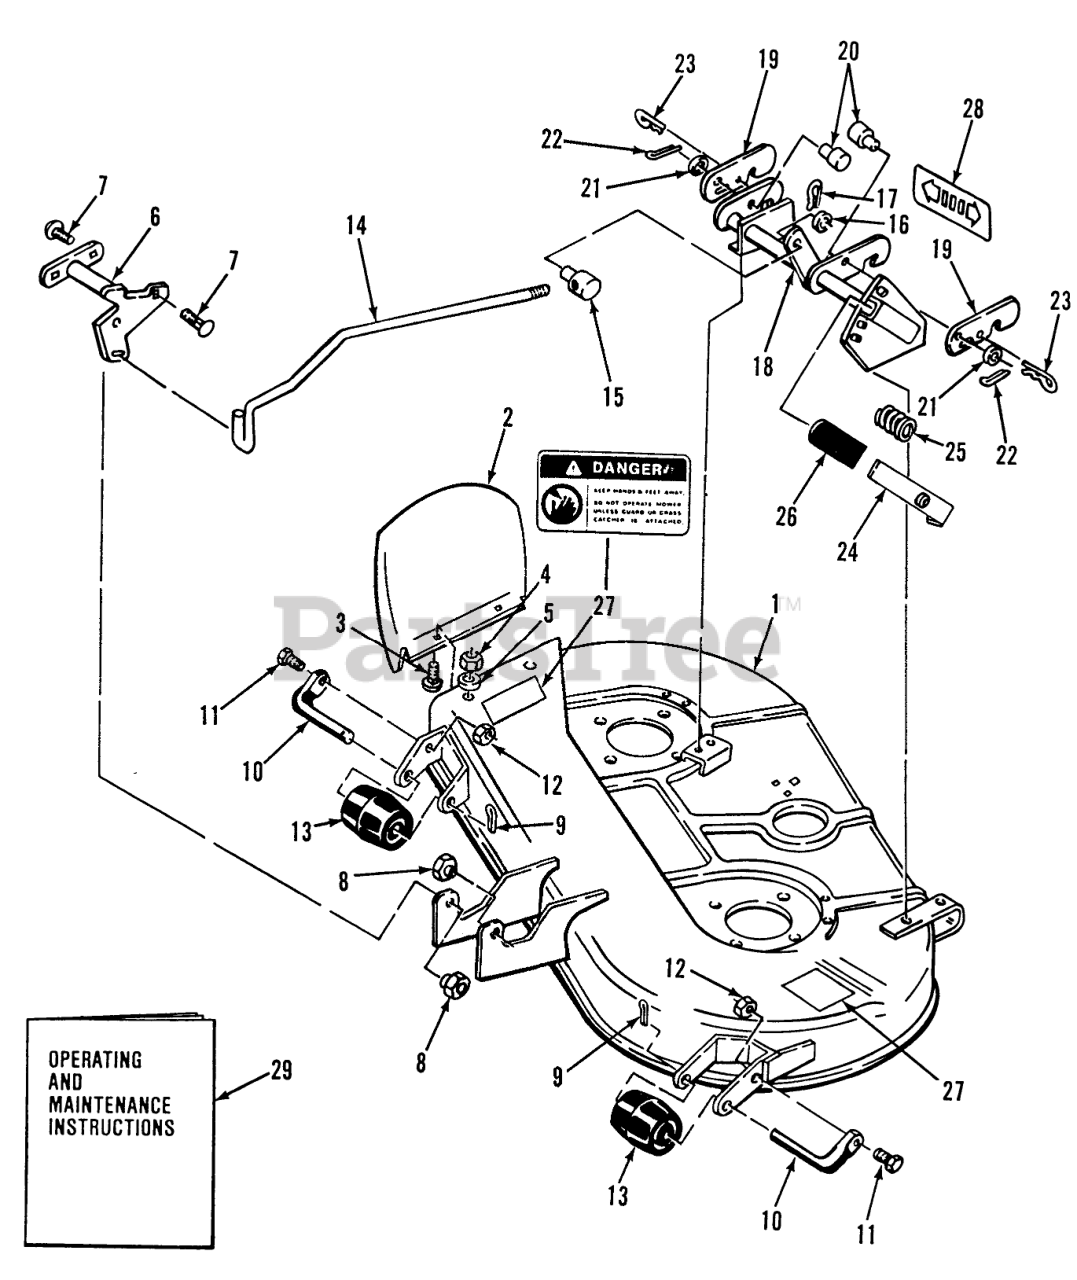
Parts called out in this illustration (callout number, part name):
2	Chute Extension
3	Bolt
4	Nut
5	Collar
9	Cotter Pin
10	ROLLER-SHAFT
11	Bolt
12	Nut
13	Roller
15	STUD-TRUNION
16	Washer
17	Hairpin Cotter
19	Latch
21	Washer
22	Cotter Pin
24	LEVER ASSY
25	SPRING-COMPRESSION
27	Danger Decal
28	DECAL-HOC
